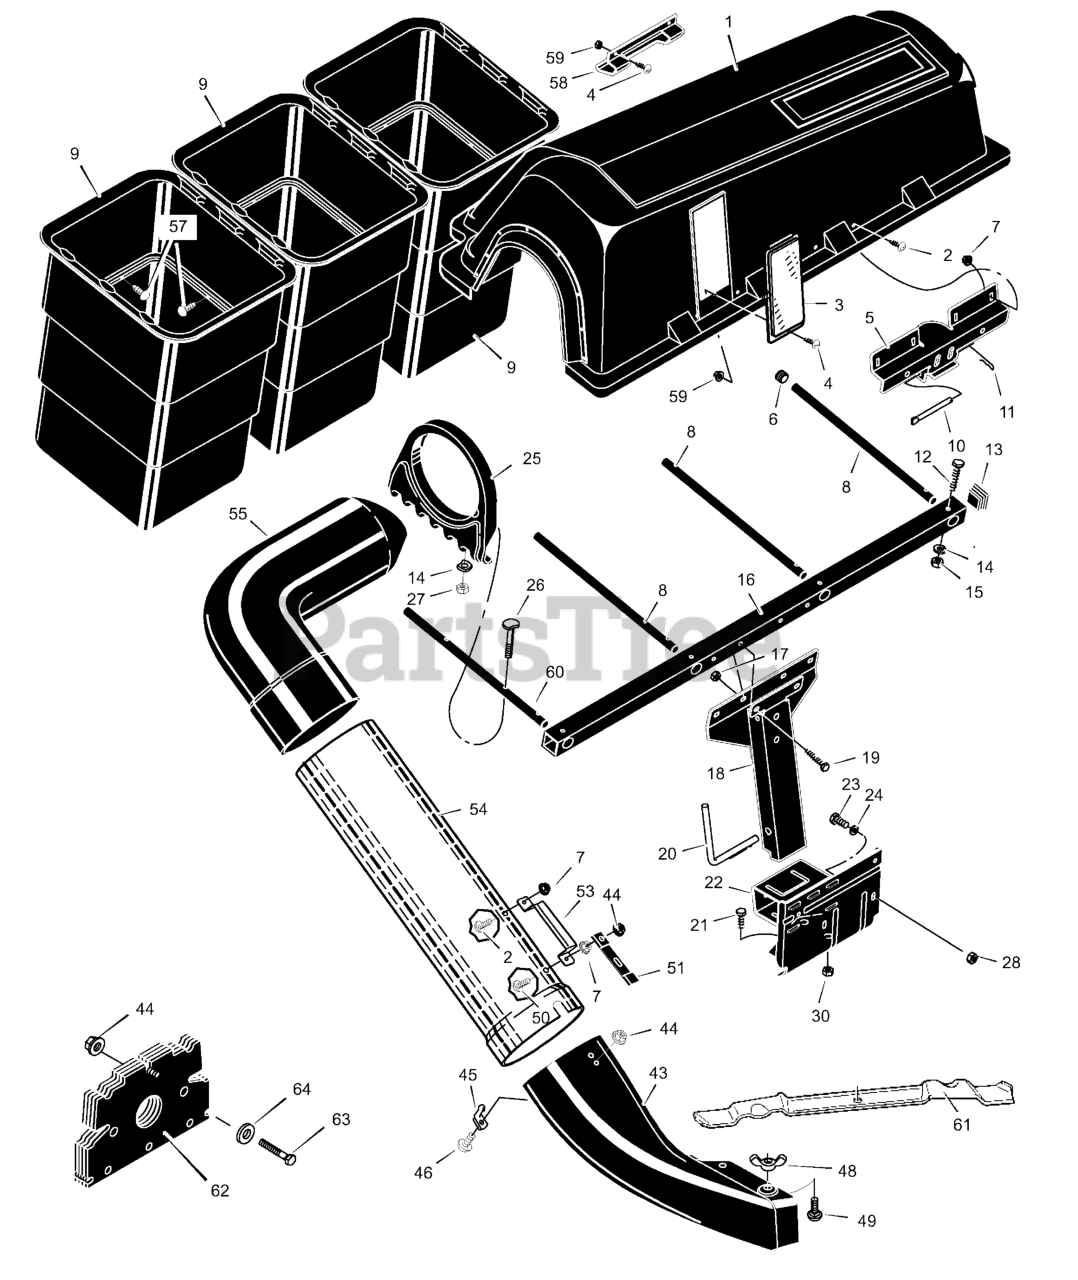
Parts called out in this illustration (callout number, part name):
1	Cover, Bagger
5	Hinge, Bracket
7	Nut, Hex
8	Tube, Container
9	Container
10	Pin, Cover Hinge
11	Pin, Hair
13	Plug
14	Lockwasher
16	Tube, Support
17	Nut
18	Assembly, Channel
20	Pin, Channel Mount
21	Bolt, Hex
22	Assembly, Bagger Mount
23	Bolt, Hex
25	Holder, Elbow
27	Washer
28	Nut, Super Flange
30	Nut, Hex
43	Tube, Extension
44	Locknut, Flange
45	Pin, Latch
46	Bolt, Carriage
48	Wingnut
49	Bolt, Carriage
51	Latch, Rubber
53	HANDLE, Connect Tube
54	Tube, Connecting
57	Fastener, Panel
58	Handle, Plastic
59	Nut, Hex
60	Tube, Right Container
61	Blade, High Lift
62	Weight, Front
